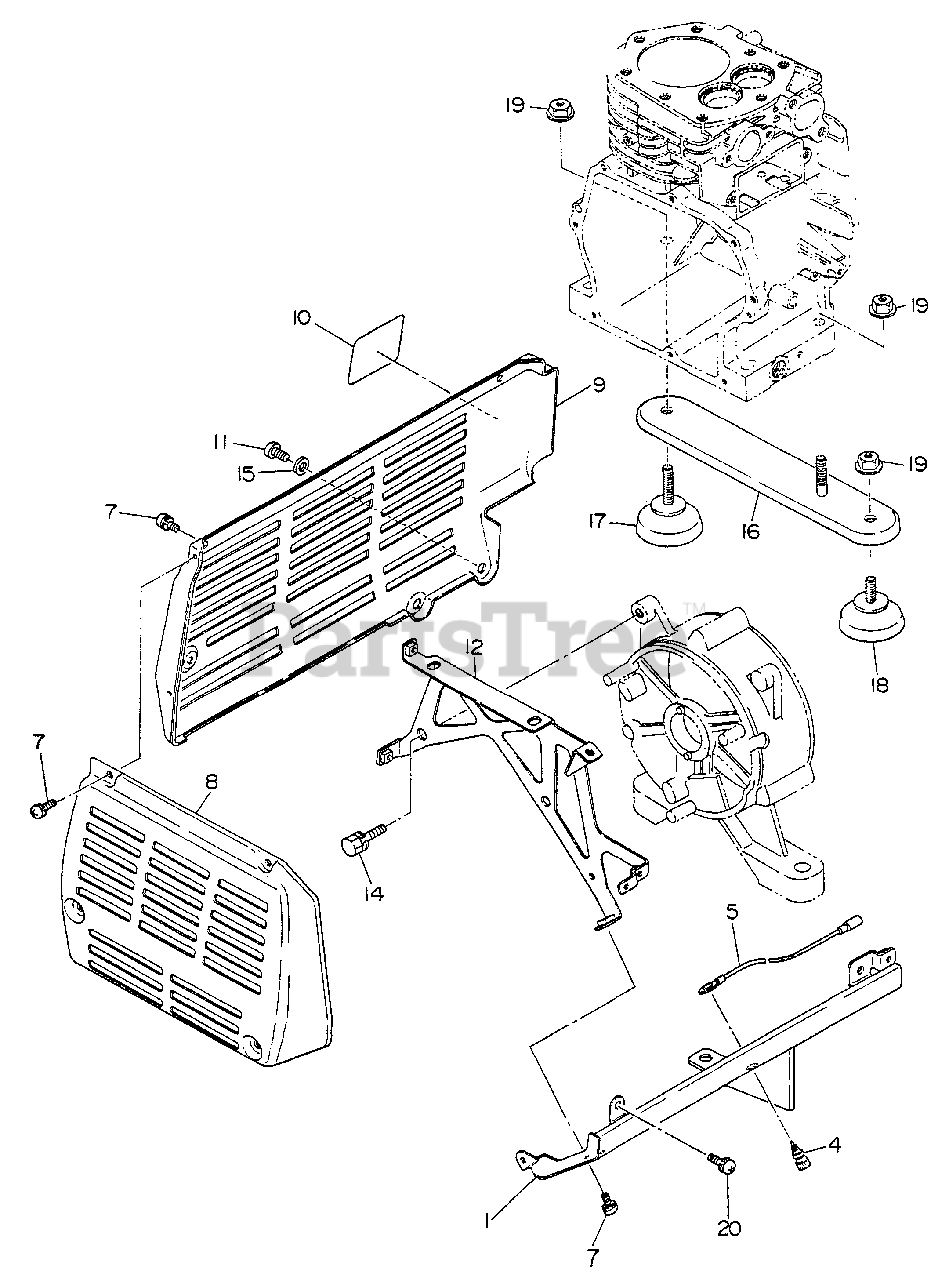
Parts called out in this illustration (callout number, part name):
1	FRONT COVER ASSY
4	BOLT, TERMINAL - BLACK
5	LEAD - GROUND
7	SCREW
8	SIDE COVER
9	COVER ASSY - REAR
10	LABEL - SPECIFICATION
11	SCREW
12	MOUNT ASSY
14	BOLT
15	WASHER
16	MOUNT ASSY
17	MOUNT ASSY
18	MOUNT ASSY
19	NUT - 8 -- FLANGE
20	SCREW
